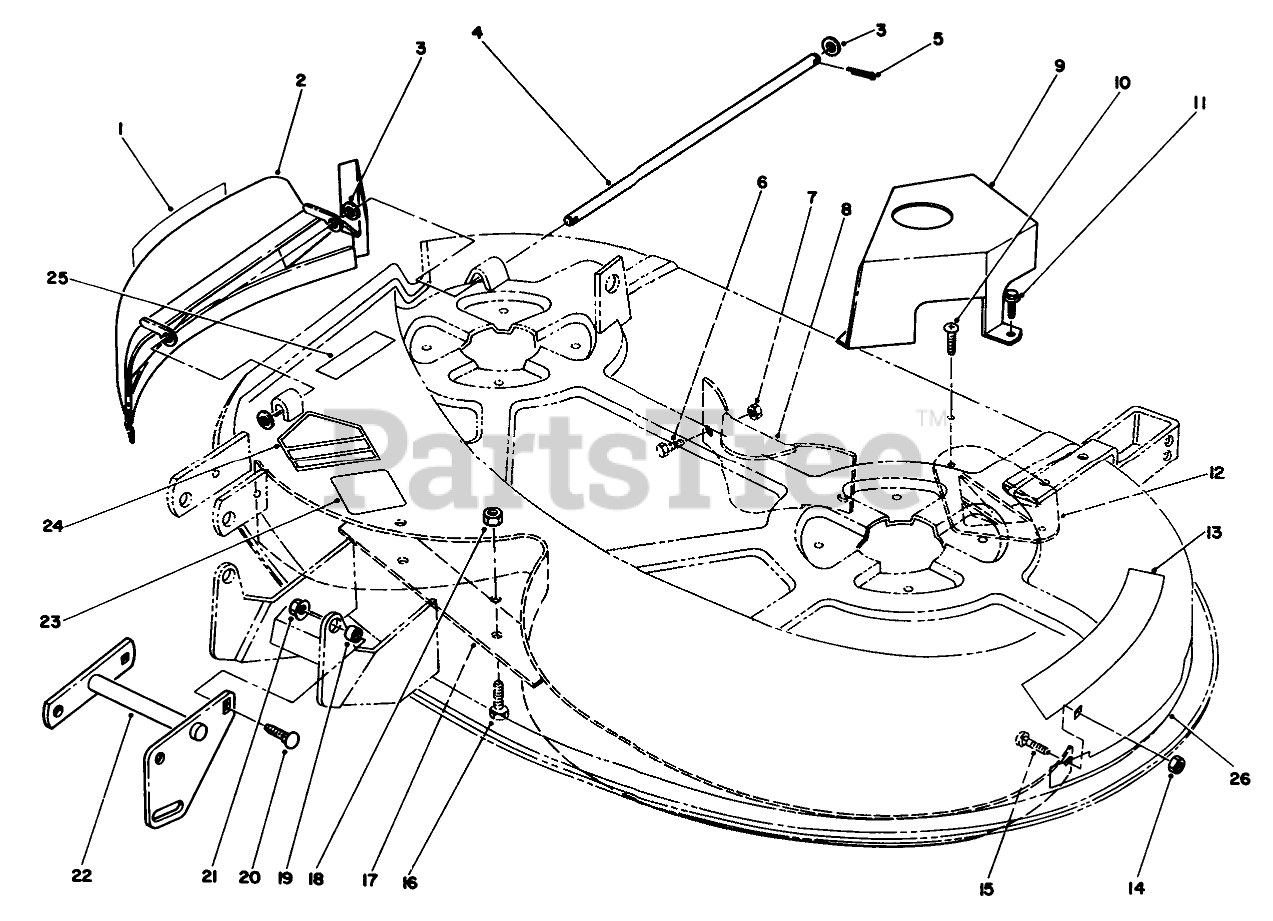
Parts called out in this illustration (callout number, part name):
1	DECAL-DANGER, THROWN OBJECT
2	Chute-Recycler
3	WASHER 5/16 SAE
5	Cotter Pin
6	H H C S
7	Nut
8	Baffle-Rear
9	COVER-BELT R
10	#8 X .625" PHILPS PAN H
11	SCREW-HWHTF
12	PLATE-KICKER
13	DECAL-DANGER
14	Nut
15	Bolt
16	Bolt
17	Baffle-38"
18	NUT
19	SPACER
20	Bolt-Carriage
21	Nut-Hex Flange Lock
22	ASM-FRONT LIFT R
23	Decal-Routing
24	DECAL-DANGER
25	DECAL-DANGER
26	DECAL-38" RECYCLER
